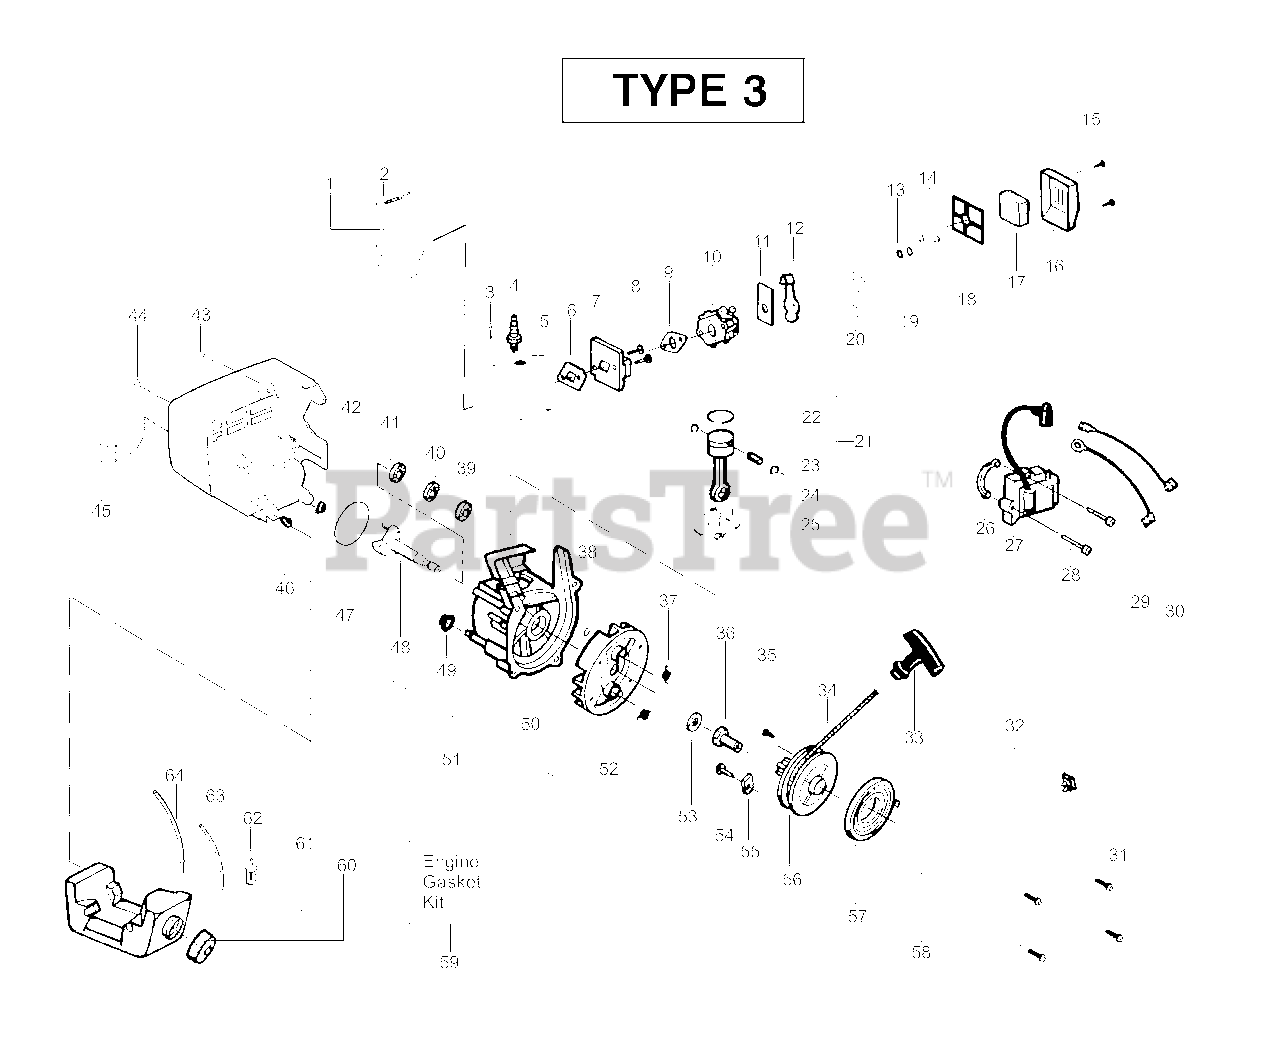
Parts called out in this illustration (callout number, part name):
1	Kit - Muffler
2	Muffler Spring
3	Screw-Cylinder
4	Spark Plug (RCJ 6Y)
5	Kit - Cylinder
6	Gasket-Cyl/Carb.(kit)
7	Adaptor-carb.
9	Gasket-Carb.(kit)
10	Kit-Carb. (WA226)
11	Plate-Choke Mounting
12	Lever-Choke
16	Cover-Air Box
17	Foam-Air Filter
18	Plate-Air Filter Support
19	Spacer-Choke
21	Kit - Piston
22	Piston Ring
23	Retainer-Piston Pin
24	Assy-Connecting Rod
25	Gasket-Cylinder(kit)
26	Spacer-Module
27	Ignition Module
29	Assy-Ground Wire
30	Assy-Leadwire
31	Screw
32	Kit-Switch
33	Handle-Starter
34	Kit - Rope
36	Coupling-Drive
37	Spring-Starter Dog
38	Retain. Ring-C'shaft
39	Bearing-Outer
40	Kit-Seal C'case
41	Bearing-Inner
44	Screw
45	Guard-Muffler
46	Isolator-Shroud
47	O-Ring-C'case (kit)
48	Assy-Crankshaft
49	Isolator-Crankcase
50	Assy-Crankcase
51	Assy-C'case & C'shaft
52	Assy-Flywheel
53	Washer-Flat
55	Retainer-Pulley
56	Kit-Starter Pulley
57	Spring-Starter
58	Assy-Fan Housing
59	Kit-Engine Gasket
60	Assy-Fuel Cap
61	Assy-Fuel Tank
62	Assy-Fuel Pickup
63	Kit-Fuel Line
64	Kit-Fuel Line
